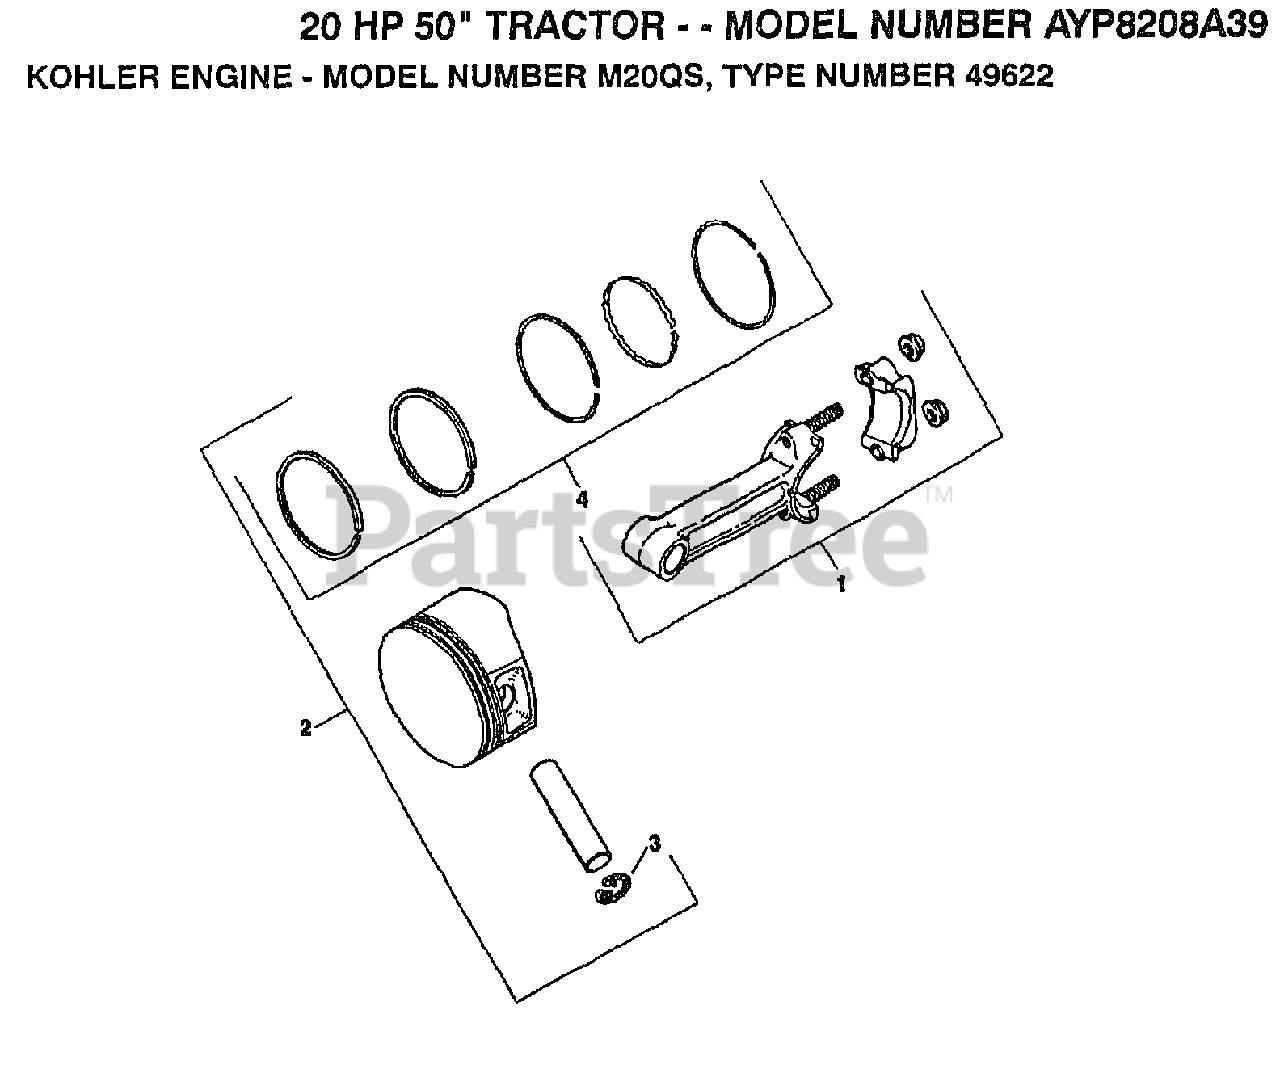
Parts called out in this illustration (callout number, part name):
1	CONNECTING ROD, STANDARD
1	CONNECTING ROD
2	PISTON WITH RING SET, STANDARD
2	PISTON WITH RING SET
3	RETAINER, PISTON PIN
